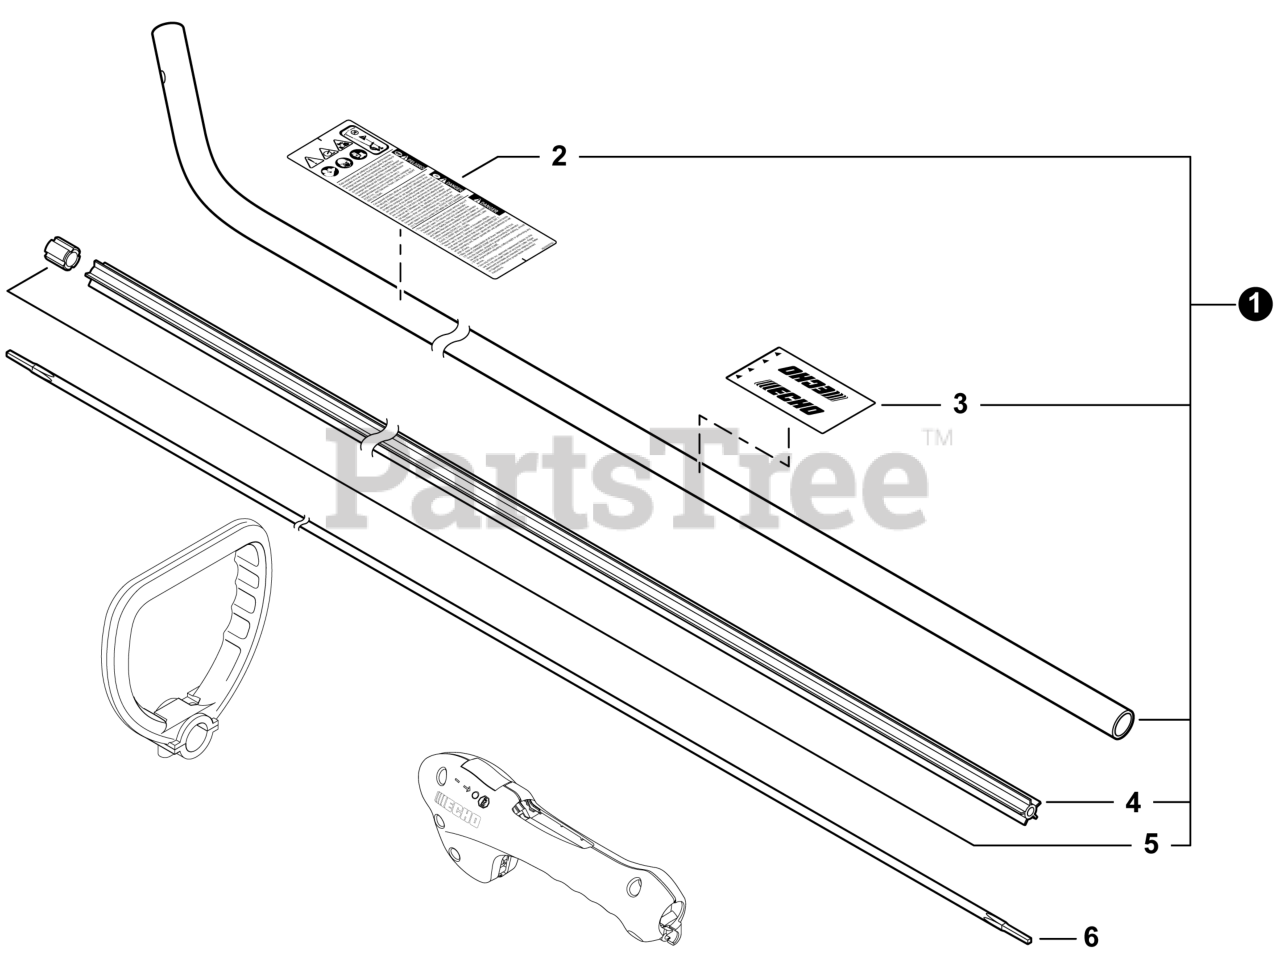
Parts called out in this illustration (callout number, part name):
1	MAIN PIPE ASSY
2	LABEL - CAUTION
3	LABEL - HANDLE LOCATION
4	LINER, FLEXIBLE 21.6x1420
6	DRIVESHAFT - FLEXIBLE
